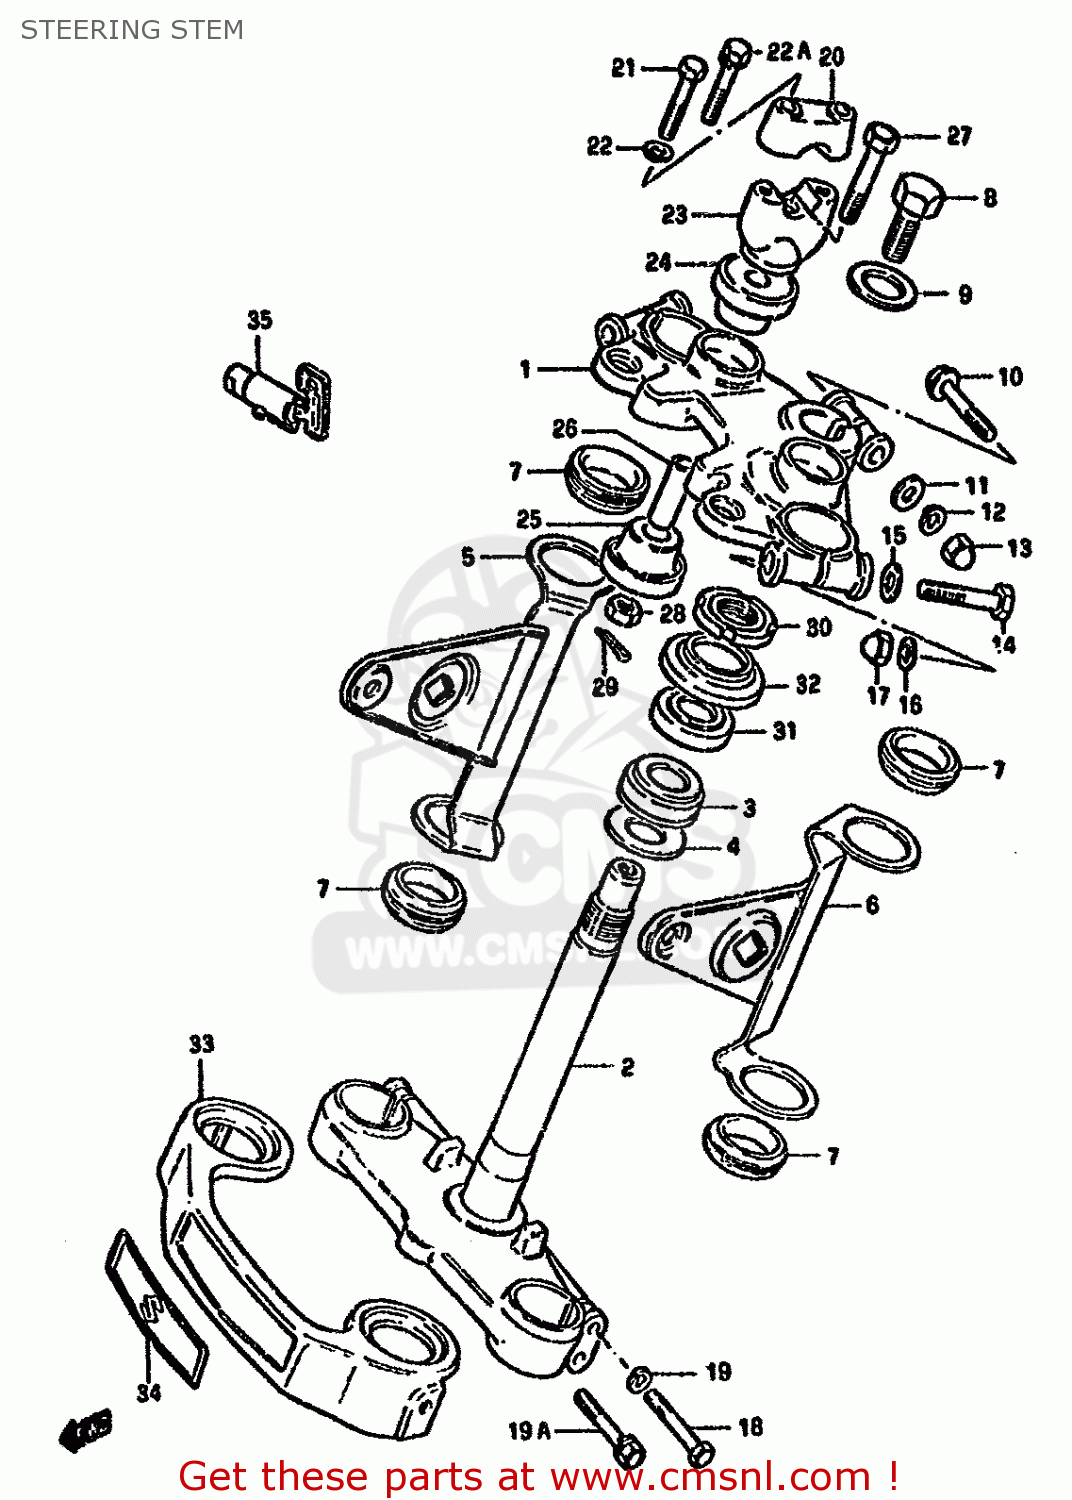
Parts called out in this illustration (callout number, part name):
1	HEAD,STEERING STEM
2	STEM,STEERING
3	BEARING(30X55X17)
4	WASHER,THRUST
5	BRACKET,HEADLAMP,R
6	BRACKET,HEADLAMP,L
7	CUSHION,HEADLAMP BRACKET
8	BOLT(12X20)
9	WASHER (12.5X27X1.6)
10	BOLT, UPPER
11	WASHER
12	WASHER,LOCK,8.
13	NUT,M8X1.25X12
14	BOLT 10X55
15	WASHER 10MM
16	LOCK WASHER
17	NUT 10MM
18	BOLT
19	LOCK WASHER
19A	BOLT
20	HOLDER,HANDLE UPR
21	BOLT
22	LOCK WASHER
22A	BOLT
23	CLAMP,HANDLEBAR,LOWER
24	CUSHION,UPR
25	CUSHION
26	SPACER(10.2X14X46)
27	BOLT(10X78)
28	NUT
29	COTTER PIN
30	NUT,STEERING STEM(25X44X10)
31	TAPER,ROLLER BEARING
32	SEAL,STEERING UPR DUST
33	COVER,FR FORK
34	EMBLEM,FR FORK COVER
35	LOCK ASSY,STEERING(NEIMAN)
